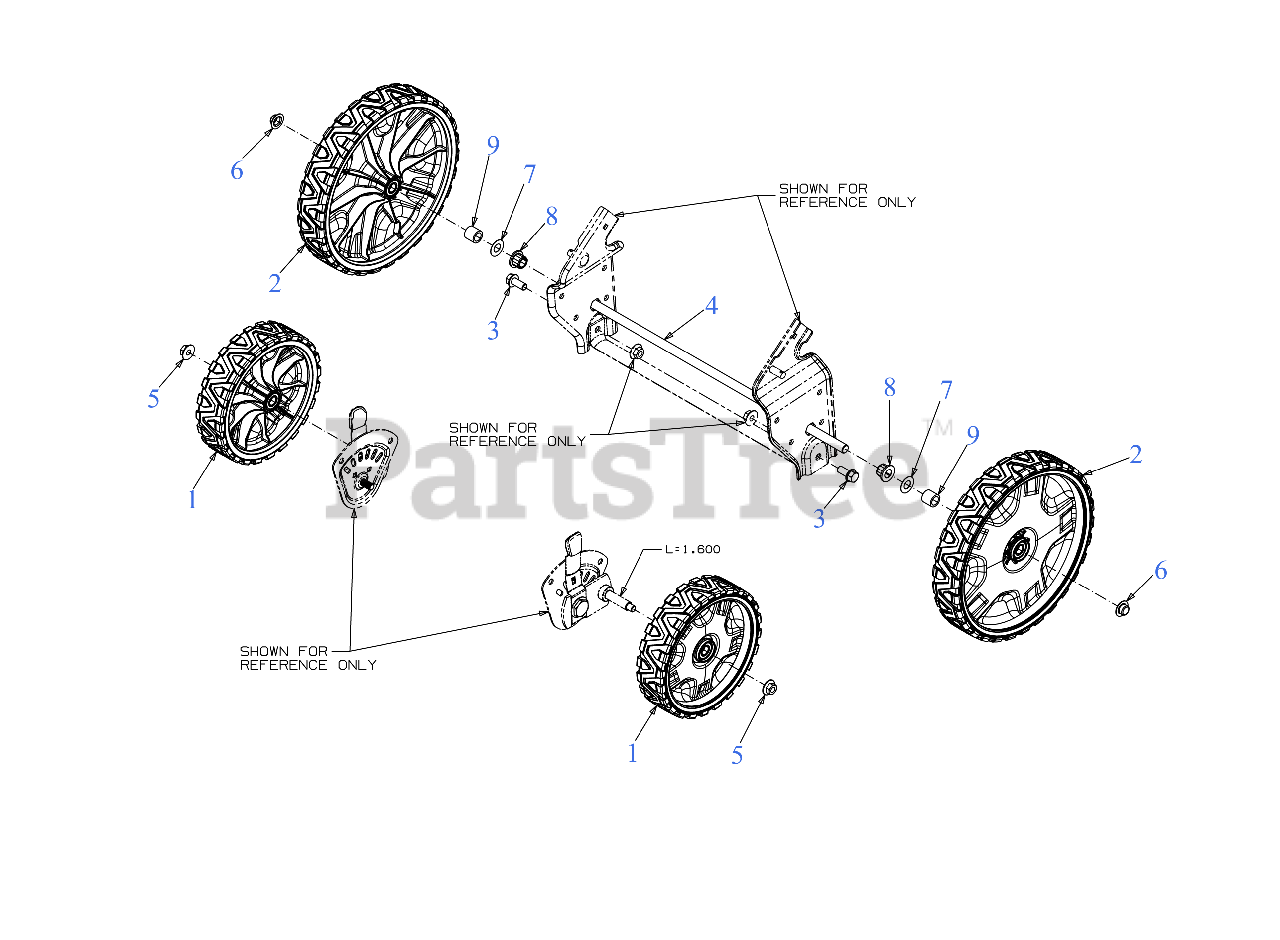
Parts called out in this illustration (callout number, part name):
1	WHEEL ASSEMBLY (8 x 2)
2	IDLE WHEEL 11 x 2 BB
3	SCREW 3/8-16 x .875 GR5
4	REAR AXLE .50 x 22.53 CSV
5	FLANGE LOCK NUT
6	PUSH CAP
7	FLAT WASHER
8	HEX FLANGE BEARING .506ID x .590LG
9	SPACER-.513 ID x .703 OD x .69
